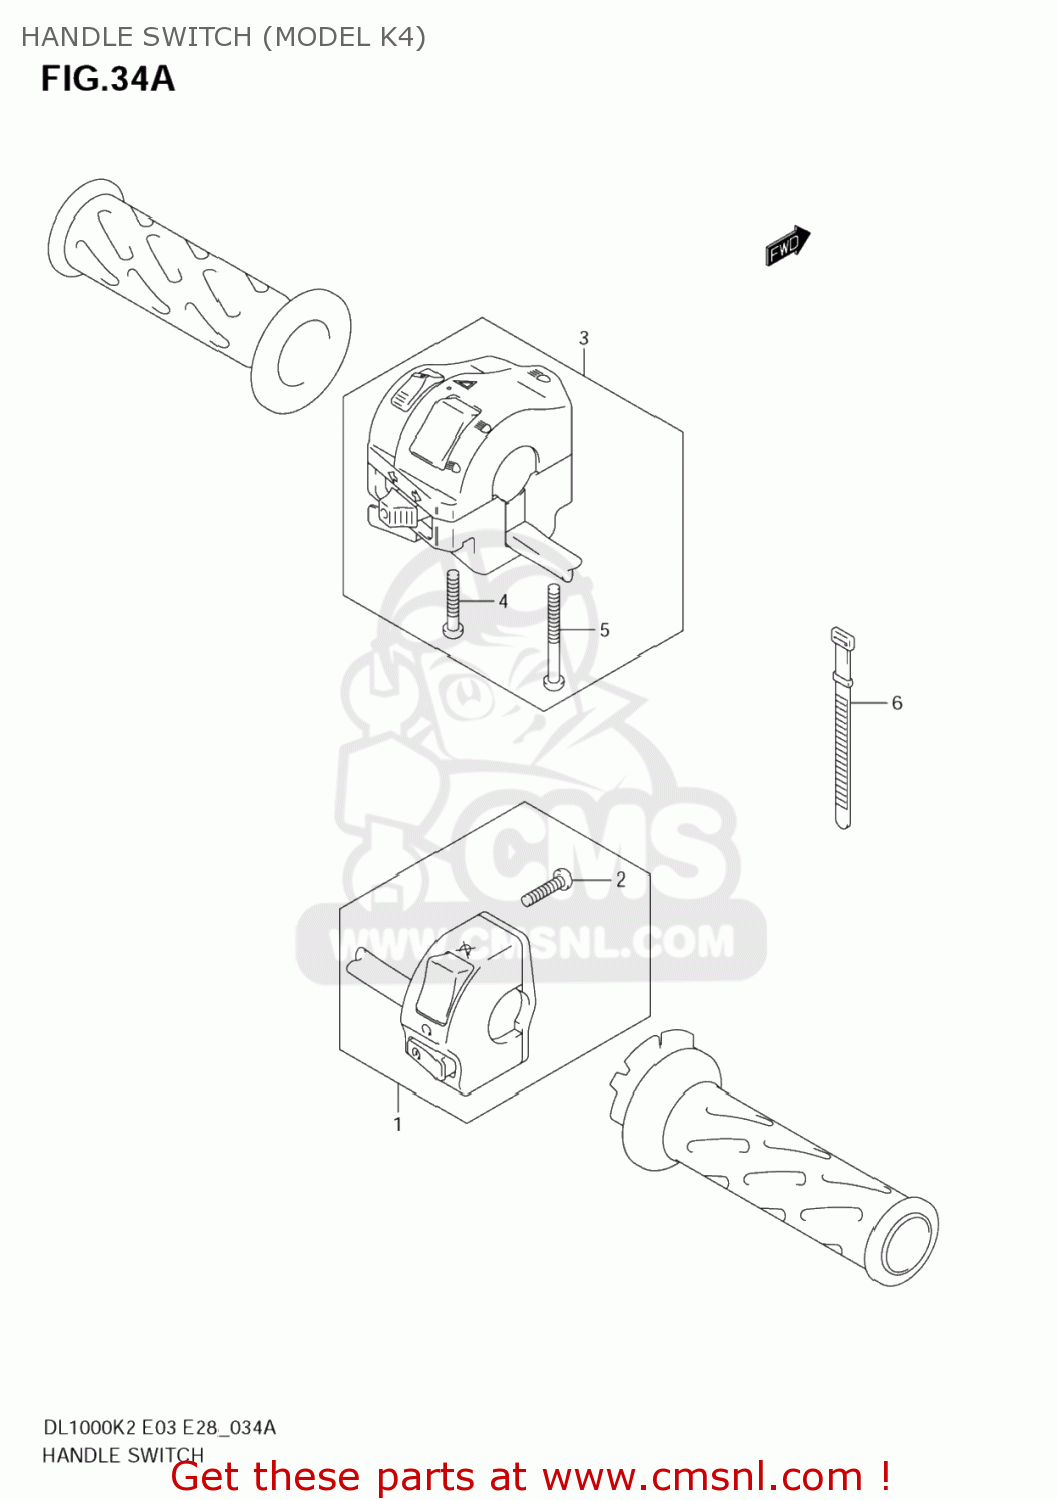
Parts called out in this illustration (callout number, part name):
1	SWITCH ASSY,HANDLE,R
2	SCREW
3	SWITCH ASSY,HANDLE,L
4	SCREW
5	SCREW
6	CLAMP(L:120)
